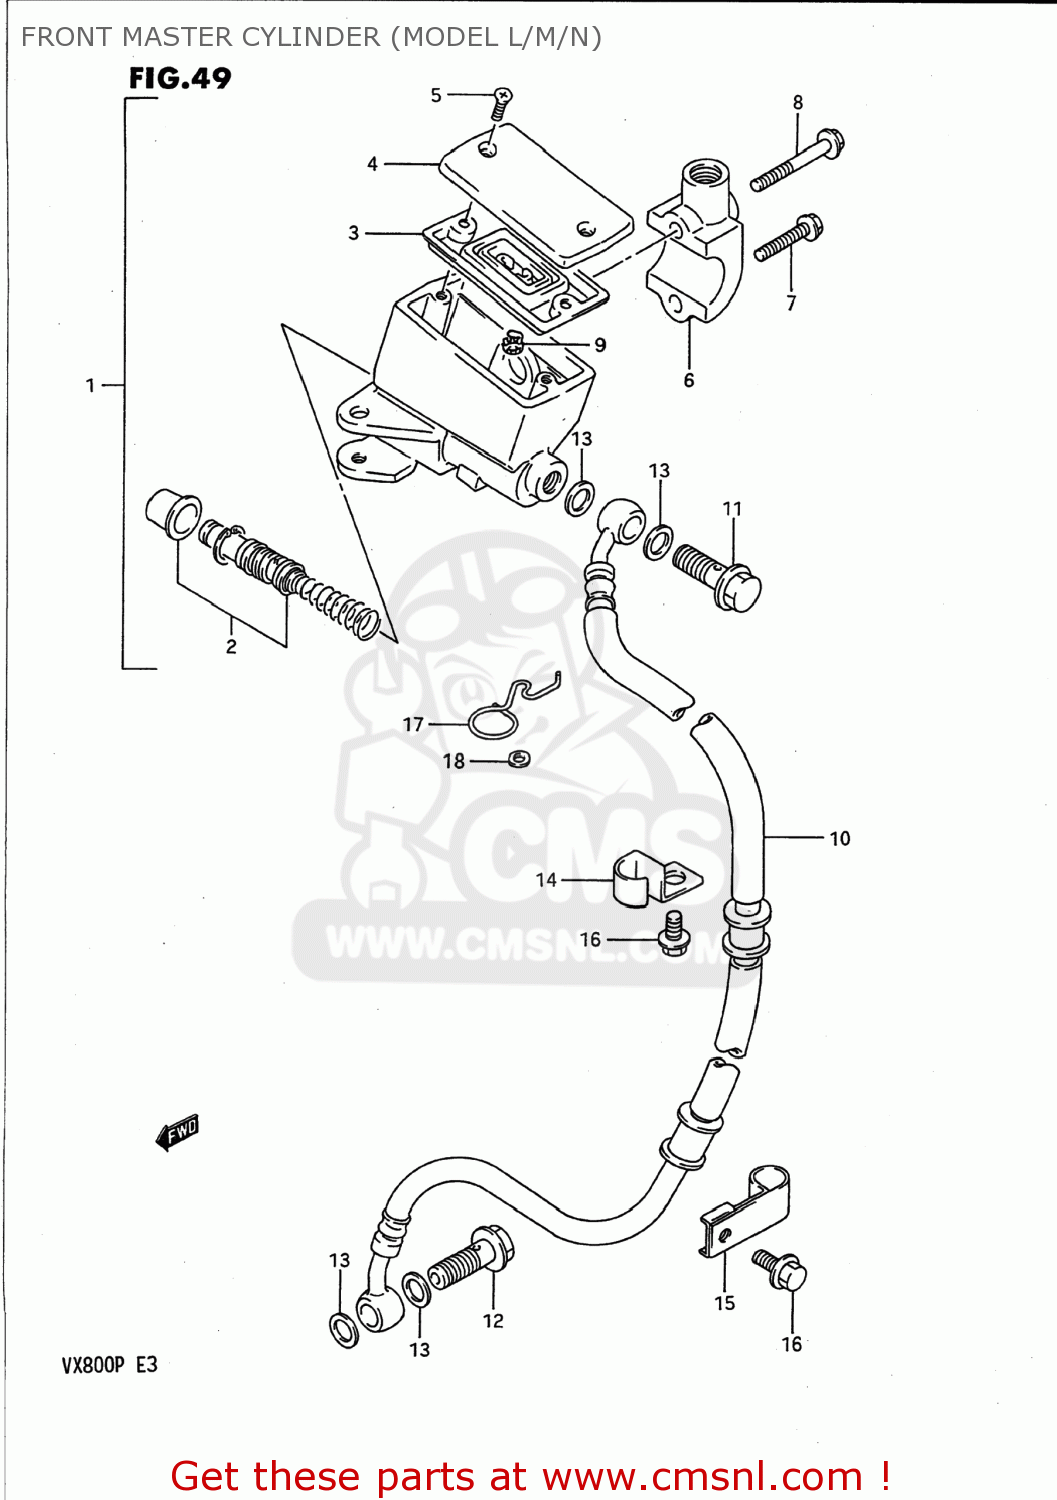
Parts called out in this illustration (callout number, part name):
1	CYLINDER ASSY,FR MASTER
2	PISTON/CUP SET
3	4-1
4	LAMP
5	SCREW
6	HOLDER
7	BOLT(6X25)
8	BOLT(6X38)
9	PROTECTOR
10	HOSE COMP,FRONT BRAKE
11	BOLT UNION
12	BOLT 10X1.25X24
13	WASHER(10X15X1.5)
14	CLAMP,FR BRAKE HOSE NO.1
15	CLAMP,FRONT BRAKE NO.2
16	BOLT 6X12
17	GUIDE,FRONT BRAKE HOSE
18	WASHER
